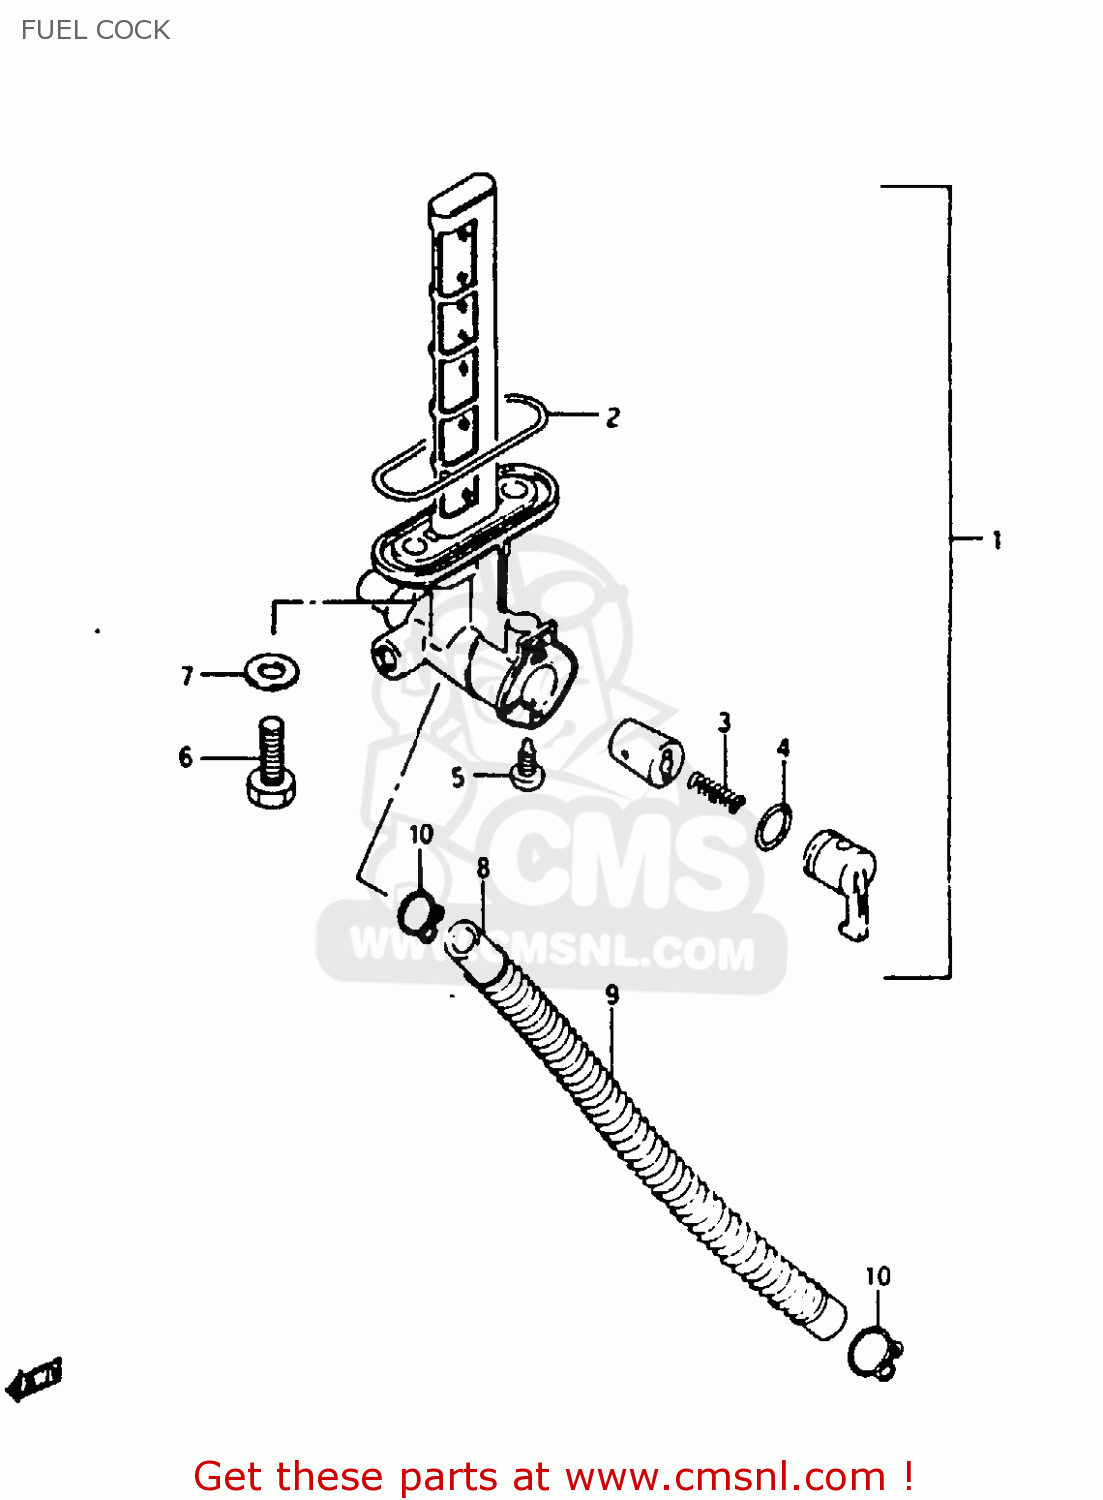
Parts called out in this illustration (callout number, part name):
1	COCK ASSY, FUEL
2	O RING,FUEL COCK
3	SPRING
4	O-RING
5	SCREW
6	BOLT(6X20)
7	GASKET
8	HOSE
9	SPRING
10	CLIP
